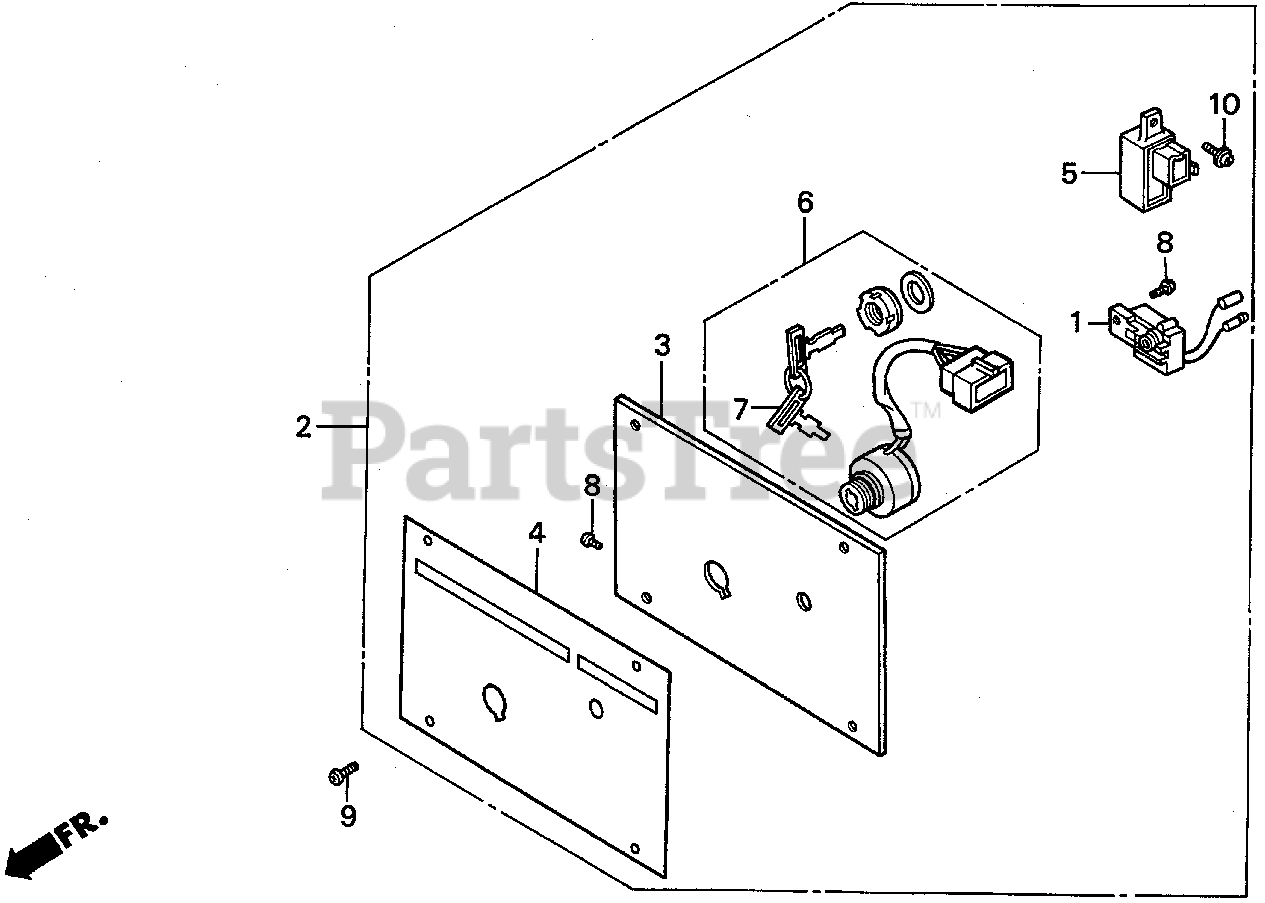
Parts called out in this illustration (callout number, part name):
1	ALERT UNIT, OIL
2	PANEL ASSY., ENGINE SWITCH (EXW-A)
3	PANEL, ENGINE SWITCH (EXW-N)
4	PLATE, ENGINE SWITCH INDICATION (EXW-A)
5	DIODE ASSY.
6	SWITCH ASSY., COMBINATION
7	KEY
8	SCREW, PAN (4X8)
9	SCREW, PAN (5X10)
10	SCREW-WASHER (4X12)
